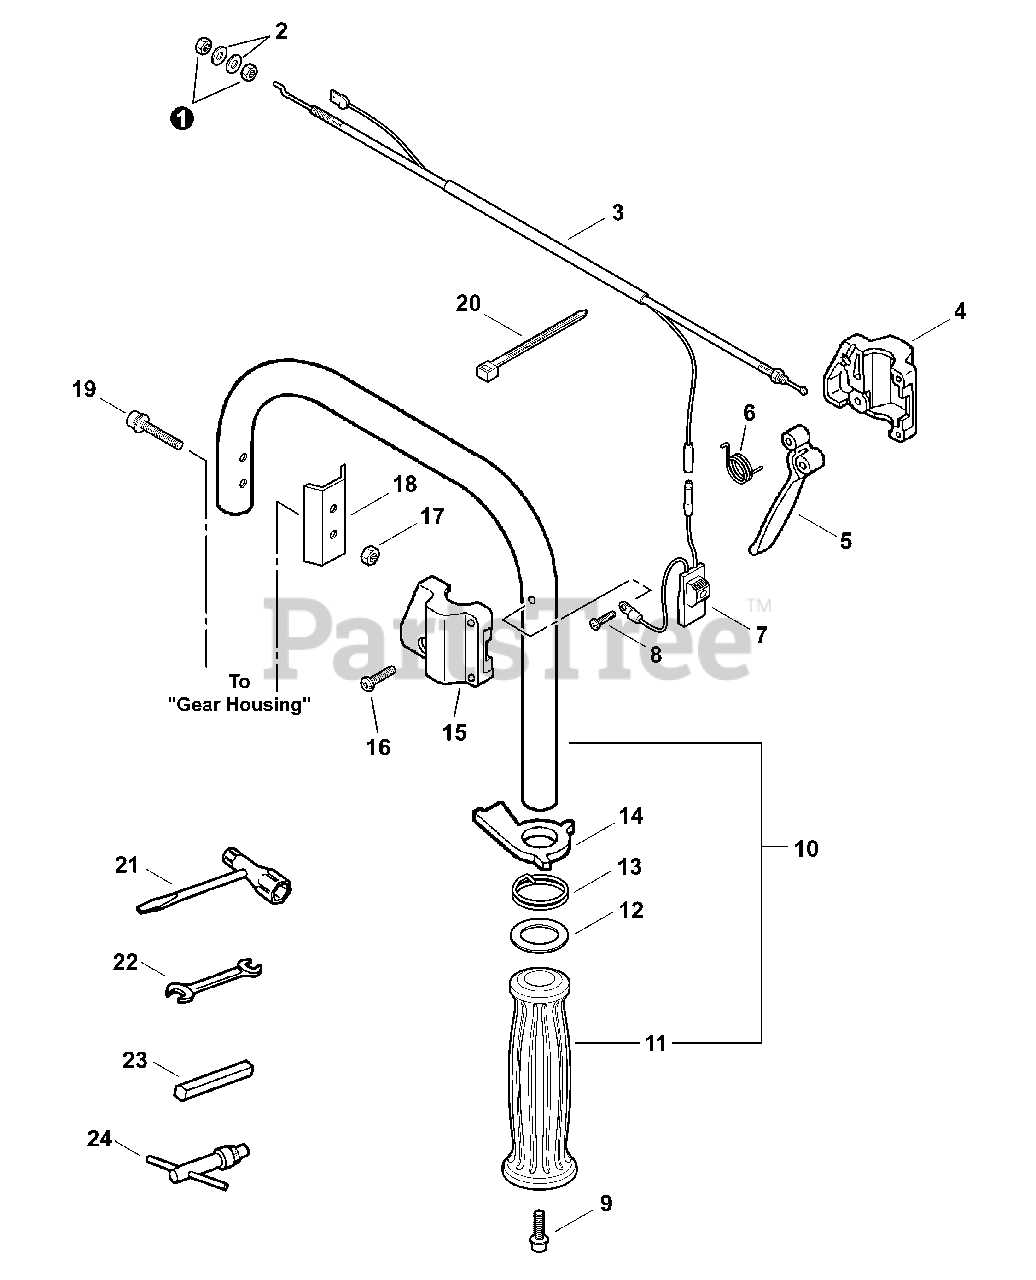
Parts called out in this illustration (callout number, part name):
2	WASHER 6.5×11.5×0.8
3	CONTROL CABLE ASSY
4	BRACKET, THROTTLE CONTROL - RIGHT
5	CONTROL, THROTTLE
6	SPRING, THROTTLE RETURN
7	SWITCH, ON-OFF
8	SCREW 4×30
9	SCREW 5×16
10	HANDLE ASSY - REAR
11	GRIP, HANDLE
13	SPRING, THROTTLE LOCKOUT
14	LOCKOUT, THROTTLE
15	BRACKET, THROTTLE CONTROL - LEFT
16	SCREW 4×25
17	NUT, LOCK M5
19	BOLT M5×35
20	TIE, CABLE
21	T-WRENCH 10×19 MM
22	SPANNER 17×19
23	BAR, HEX
24	KEY, CHUCK
